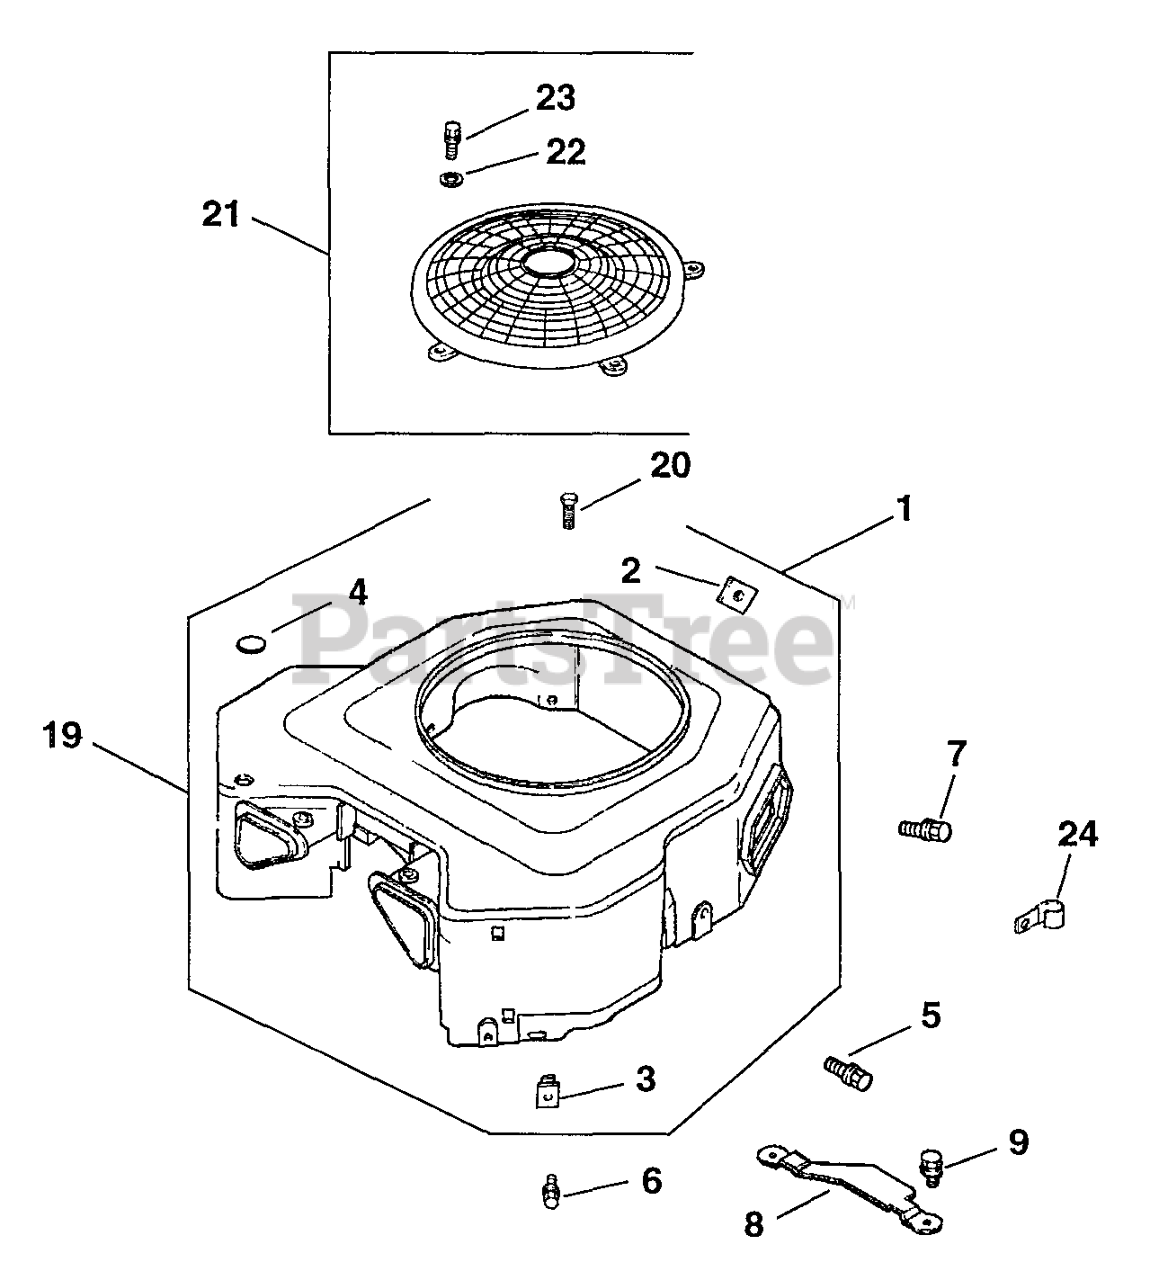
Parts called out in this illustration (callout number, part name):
2	Nut, Plastic
3	Nut, Plastic
4	Plug, Button 9/16"
5	Screw, Hex. Flange M5x0.8x16
6	Screw, Hex. Flange M5x0.8x20
7	Screw, Hex. Flange M5x0.8x16
8	Guard, Flywheel
9	Screw, Hex. Flange M6x1.0x16
19	Housing, Blower
20	Screw, Hex. Socket Hd. 10-24x1/4"
